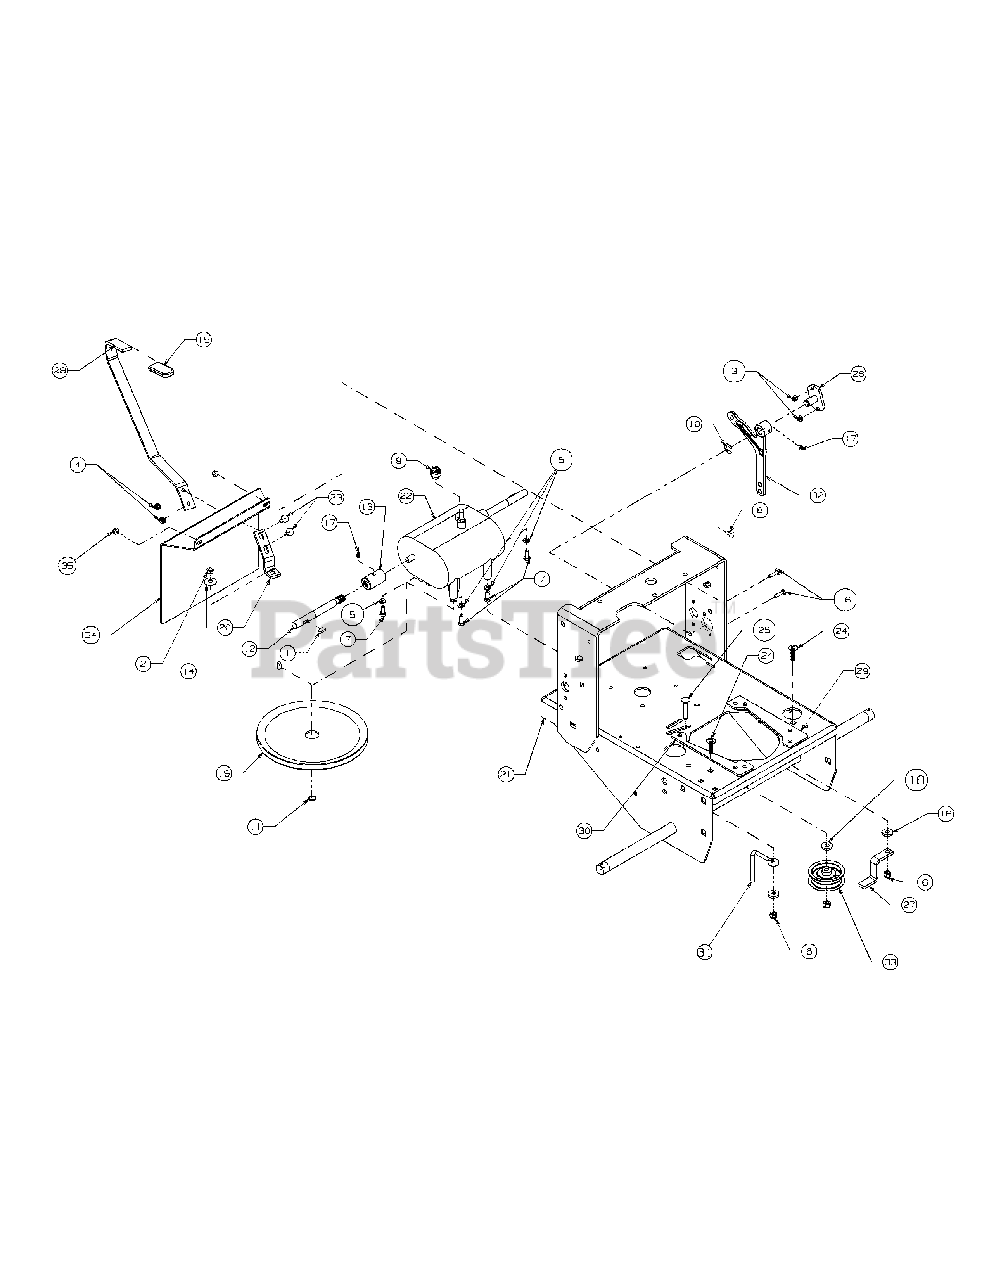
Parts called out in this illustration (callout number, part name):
1	Woodruff Key, 3/16 x 3/4
2	Jam Nut, Insert Lock, 3/8-24
3	Lock Nut, Nylon Insert, 1/4-20
4	Nut, 5/16-18 Nylock
5	Lock Washer, 5/16 Zinc
6	Lock Nut, Nylon Insert, 3/8-16
7	Hex Cap Screw, 5/16-18 x 3/4
8	Carriage Bolt, 1/4-20 x .750
9	Switch, WB Transmission
10	E-Ring, 5/8
11	External Retainer Ring
12	Jackshaft w/ Heavy Spline
13	Coupling w/Heavy Spline
14	Bell Washer, .39 ID x 1.13 OD x .062
15	Grip, .250 x 1 x 3-1/2, Yellow
16	Carriage Bolt, 1/4-20 x 1.00
17	Grease Fitting, 1/4-28 x 3/16
18	Idler Washer
19	Transmission Pulley
20	Shift Arm
21	Engine Deck Assembly
22	Transmission, 5 Speed
23	Carriage Bolt, 5/16-18 x 1
24	Carriage Bolt, 3/8 -16 x 1.25
25	Carriage Bolt, 3/8-16 x2
26	Bellecrank Pivot, Weldment
27	Engine Belt Guide
29	Engine Spacer, LH
30	Engine Spacer, RH
31	Drive Belt Guide
32	Clutch, Bellecrank Casting
33	Flat Idler Pulley w/Adapter
35	Lock Nut, Nylon Insert, 1/4-20
